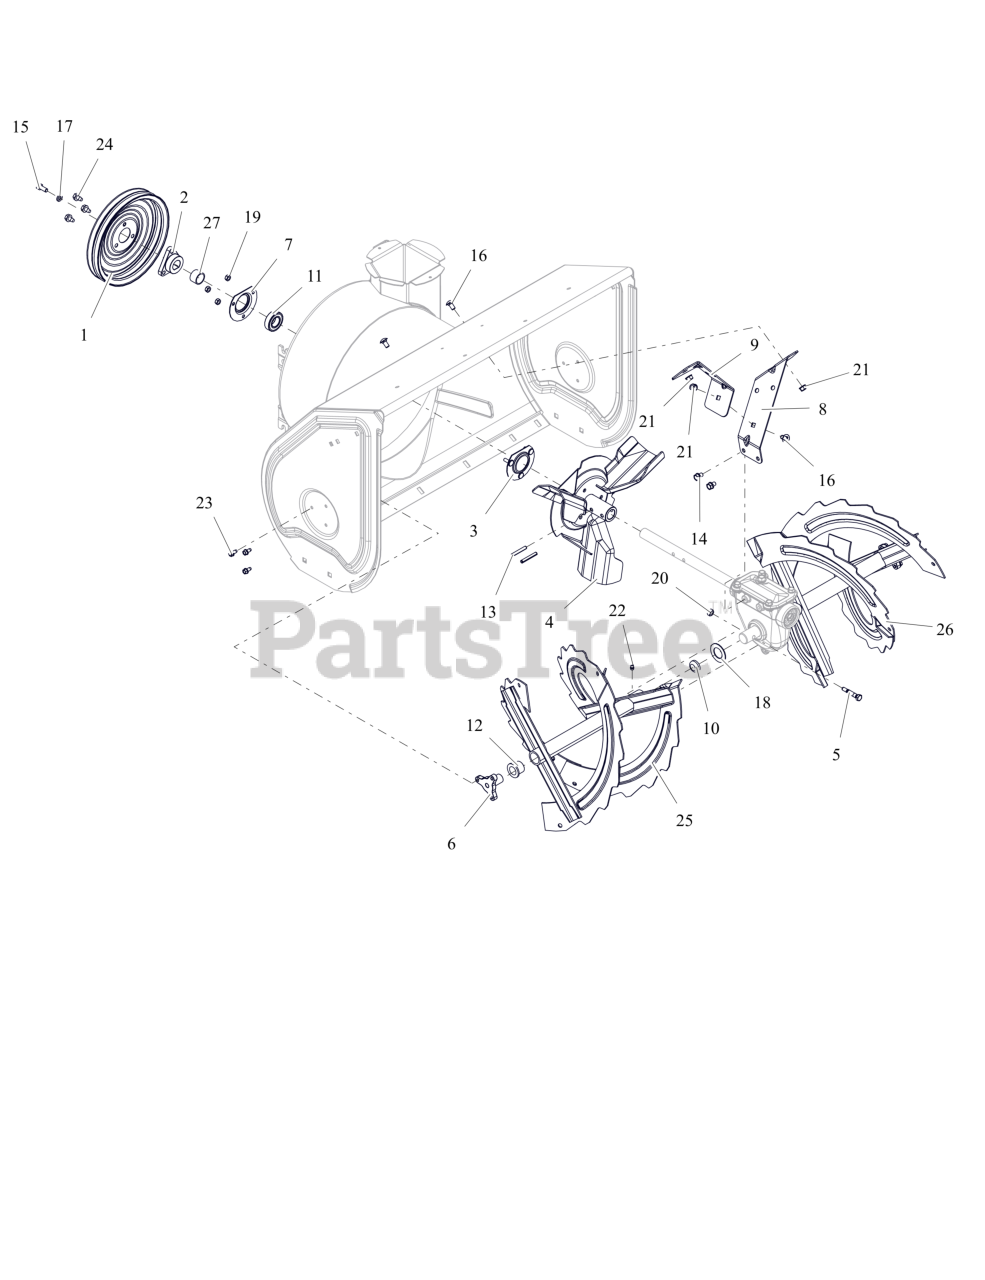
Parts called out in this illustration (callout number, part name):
1	PULLEY, SPIN FORM DUAL GROOVE
2	PULLEY HUB, D-BORE .87 PRO
3	BEARING FLANGE
4	IMPELLER, 3 BLADE-14"
5	SHEAR BOLT SERVICE ASSEMBLY
6	SUPPORT, RAKE BUSHING
7	BEARING FLANGE
8	BRACKET, GEARCASE SUPPORT - LH
9	BRACKET, GEARCASE SUPPORT - RH
10	PLUG, RAKE TUBE
11	BRG-BALL .876 X 1.750 X .50
12	BSHG-FLG, NY.778 ID X 1.018 OD
13	PIN-ROLL .250X1.75
14	BLT, SEMS .31-18X.50 G5 ZCC
15	BLT, HEX .31-24X.750 G5 ZCC
16	BLT,RHSSN.31-18X.625 G5 ZCCP30
17	WSHR, LK-HVY .312X.097 ZCC
18	WSHR- FLT 1.010X1.755X.062 ZCC
19	NUT,LK-CTR .25-20 GA ZCC
20	NUT,LK-CTR .31-18 GA ZCC
21	NUT-LK-TOP-FLG .312-18 GF ZCC
22	ZERK,FITTING .25X.125 DRIVE IN
23	SCR-TAP .25-20X.50 HWH ZCC
24	SCR,TAP .312-18X.50 HWH TR ZCC
25	RAKE, RH W/ZERK - 30"
26	RAKE, LH W/ZERK - 30"
27	BSHG,SPCR .895X1.065X.693
